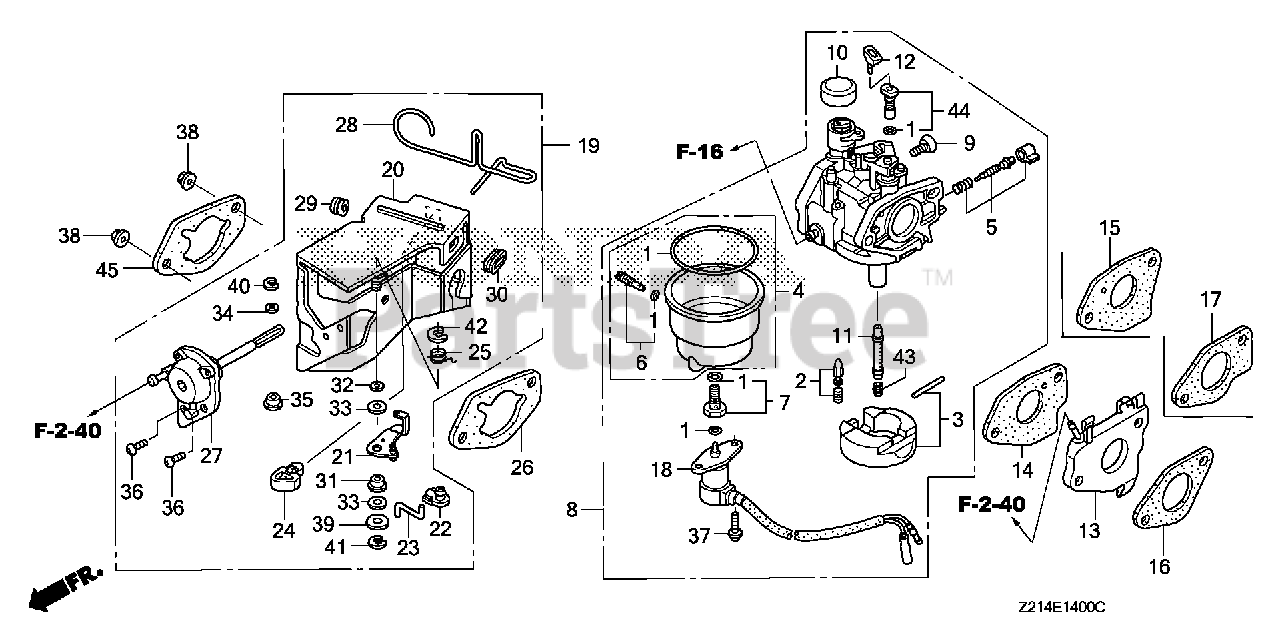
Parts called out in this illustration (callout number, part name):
1	GASKET SET
2	VALVE SET, FLOAT
3	FLOAT SET (CARBURETOR NO.)
4	CHAMBER SET, FLOAT
5	SCREW SET
6	SCREW SET, DRAIN (ADVENTURE GREEN) (CARBURETOR NO.)
7	SCREW SET B
8	CARBURETOR ASSY. (BE89J A)
9	SCREW, THROTTLE STOP
10	CAP, CHOKE LEVER DUST
11	NOZZLE, MAIN
12	COLLAR, SET
13	INSULATOR, CARBURETOR
15	GASKET, CARBURETOR
17	GASKET, INSULATOR Use up to Engine SN 2949254.
18	VALVE ASSY., SOLENOID
19	STAY ASSY., MANUAL CHOKE
20	STAY, SOLENOID
21	LEVER, CHOKE
22	JOINT, ROD
23	ROD, CHOKE
24	STOPPER, CHOKE ROD
25	SPRING, MANUAL CHOKE
26	GASKET, AIR CLEANER
27	DIAPHRAGM ASSY.
28	ROD, CHOKE CONTROL
29	GROMMET, CHOKE ROD
30	GUIDE, CHOKE ROD
31	BUSH, ARM PIVOT
32	WASHER, CHOKE LEVER
33	SEAL, CHOKE LEVER
34	WASHER, THRUST (2.7X8)
35	COLLAR, LEVER
36	SCREW, PAN (5X12)
37	SCREW-WASHER (5X12)
38	NUT, FLANGE (6MM)
39	WASHER, PLAIN (5MM)
40	E-RING (2MM)
41	E-RING (4MM)
42	E-RING (7MM)
43	JET, MAIN (#98) Use from Engine SN BE87A A to BE87A A.
43	JET, MAIN (#100) Use from Engine SN BE87A A to BE87A A.
43	JET, MAIN (#102) (ADVENTURE GREEN) (CARBURETOR NO.)
44	JET SET, PILOT (#45)
45	SPACER, CARBURETOR
